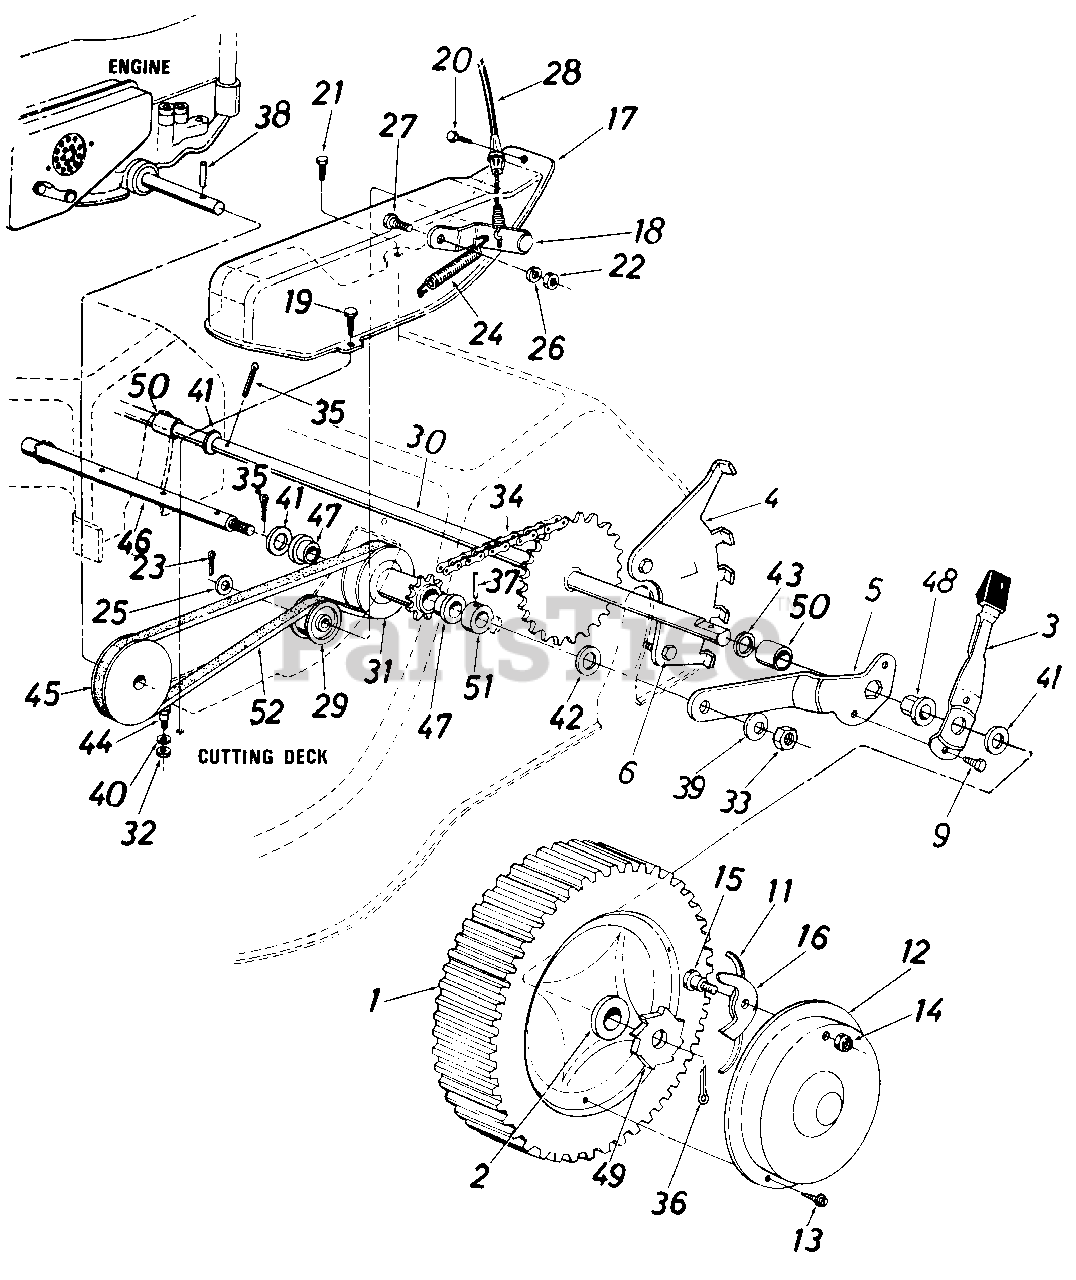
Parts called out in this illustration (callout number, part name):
1	Wheel Assy. Comp. 8.0 x
2	Flange Brg.-1/2" I.D.
3	Spring Lever w/Knob
4	Index Plate-L.H.
5	Pivot Brkt.-L.H.
6	Hex Wash. Hd. Tap Scr. 1/4 x .62" Lg.
9	Hex B-Tap Scr. 1/4 x .38" Lg.
11	Nylon Spring
12	Hub Cap
13	Pan Hd. Tap Scr. #12 x .50" Lg.
14	Hex ins. L-Nut 1/4-20 Thd.
15	Shld. Bolt .342" Dia. x .268
16	Paw I
17	Belt Cover
18	Idler Bracket Ass'y.
19	Hex Wash. Hd. Self-Tap Scr. 1/4-20 x .50" Lg.
20	Hex Drill i ng Scr. #10 x .50" Lg.
21	Hex TT-Tap Scr. 1/4-20 x .75" Lg.
22	Hex Nut 1/4-20 Thd.
23	Cotter Pin 1/8" Dia. x 1.00" Lg.
24	Extension Spring .33" O.D. x 1.12" Lg.
25	Fl-Wash. .531" I.D. x .930"O.D.
26	L-Wash. 1/4" I.D.
27	Shld. Bolt .375n Dia. x .181
28	Clutch Cable-50"
29	Flat Idler-Plastic
30	Rear Shaft Ass'y.
31	Pulley w/9 Tooth Sprocket Ass'y.
32	Hex Nut 5/16-18 Thd.
33	Hex Jam Nut 3/8-16 Thd.
34	#48 Chain 1/2" Pitch x 31 Links
35	Cotter Pin 3/32" Dia. x 1.00" Lg.*
36	Cotter Pin 1/8" Dia. x 1.00" Lg.*
37	Spring Pin Spir. 3/16" Dia. x 1.00" Lg.
38	Spring Pin Spir. 3/16" Dia. x 1.50" Lg.
39	Bell-Wash. .400" I.D. x .88" O.D.
40	L-Wash. 5/16n I.D.
41	Fl-Wash. .531" I.D. x .930" O.D.
42	Bell-Wash. .400" I.D. x 1.13" O.D.
43	Fl-Wash. .510" I.D. x 1.0" O.D.
44	Shld. Bolt .437" Dia. x .350" Lg.
45	Engine Pulley
46	Pulley Shaft-10.0" Lg.
47	Flange Brg. .506" I.D. Plastic
48	Hex Flange Brg. x .506" I.D. Plastic
49	Ratchet
50	Spacer.765" I.D. x .89" O.D. x.960" Lg.
51	Spacer. 505" I.D. x .88" O.D. x.44" Lg.
52	"V"-Belt 1/2" x 33" Lg.
